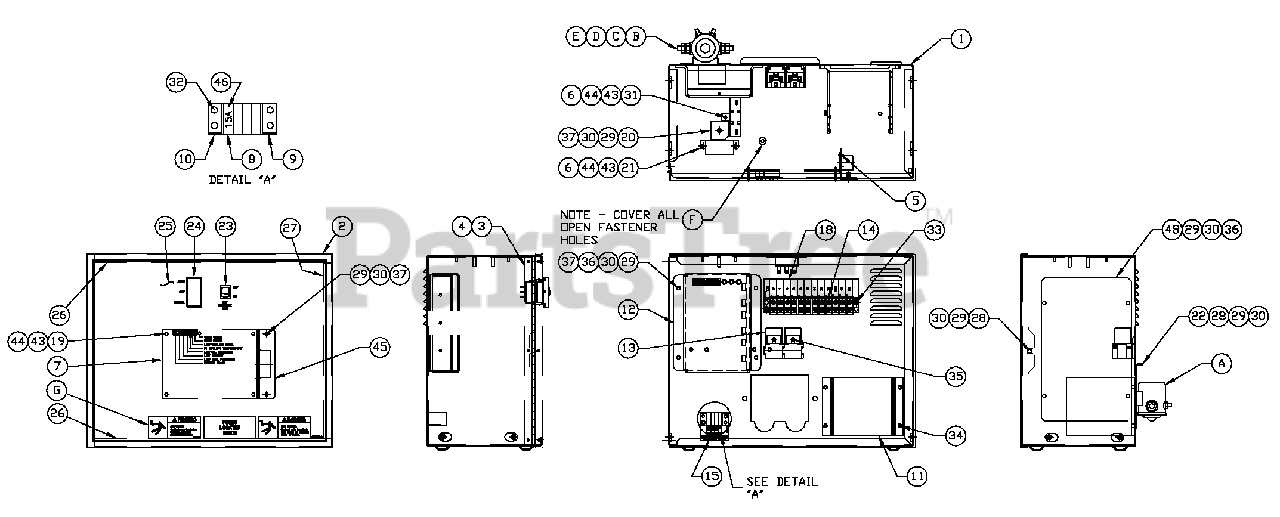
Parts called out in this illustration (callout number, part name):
1	ENCL HSB CONTROL PANEL
2	COVER CONTROL PANEL
3	HINGE CONTINUOUS H-PANEL
4	RIVET POP .125X.275SS
5	SCREW PPPH HI-LO #4-24 X 3/8
6	WASHER FLAT M3
7	ASSY PCB R-200 3600 RPM
8	HOLDER FUSE WICKMANN 178.6150
9	ADPTRRH SIDEWICKMAN 178.6191
10	ADPTR LH SIDE WICKMAN 178.6192
11	ASSY PCB 2AMP12V UL BATT CHGR
12	ASSY VOLTAGE REGULATOR 60HZ
13	RELAY 12VDC C FORM W/DIODE
14	BLOCK TERM 20A12 X 6 X1100V
15	DECAL CPL CONTROL PANEL FUSES
18	DECAL CPL 3.9LTB1
19	SPACER 9.5H 3.2 ID
20	DIO BRIDGE 25A 600V
21	CIRCT BRK 4 X1 ETA 46-500-P
22	PLATE HARNESS CLAMP
23	SWITCH RKRDPST125V SPD
24	SWITCH RKR DPDT ON-OFF-ON
25	DECAL CONTROL HSB
26	SEAL COVER3.18X12.7X382
27	SEAL COVER 3.18X12.7X283
28	SCREW HHPM M5-0.8X12
29	WASHER FLAT M5
30	WASHER LOCK M5
31	RES WW15R 5% 25W QK CONN
32	SCREW PHTTM3.5-0.6X 10
33	SCREW PHTTM3.5-0.6X 16
34	SCREW PHTTM4-0.7X 12 ZYC
35	SCREW PHTTM4-0.7X 10 ZYC
36	SCREW PPHM M5-0.8X12ZNC
37	NUT HEX M5-0.8 G8 CLEAR ZINC
43	WASHER LOCK M3
44	NUT HEX M3-0.5 G8 YEL CHR
45	SUPPORT ANGLE PCB
46	FUSE ATO TYPE 15 AMP (BLUE)
48	PLATE COVER H PANEL
A	RELAY SOLENOID 12VDC PNL MNT
B	SCREW HHC 1/4-20 X 3/4 G5
C	WASHER FLAT 1/4-M6 ZINC
D	WASHER LOCK M6-1/4
E	NUT HEX 1/4-20 STEEL
F	SEAL WEATHER .45"DIA
G	DANGER HIGH VOLTAGE (SPANISH)
